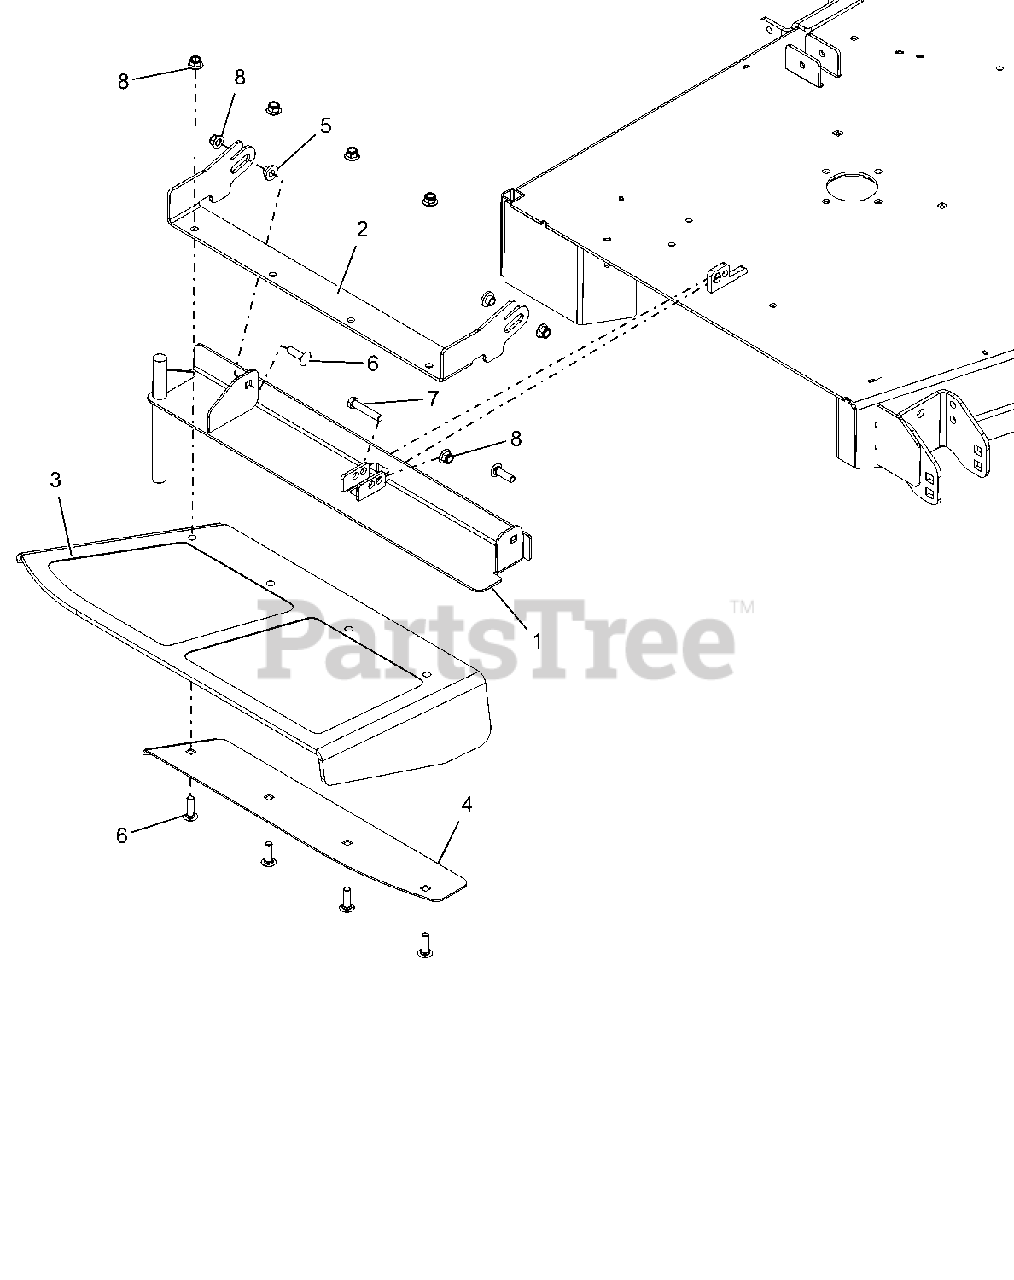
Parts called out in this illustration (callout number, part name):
1	72"DISCH CHUTE MTG WMT W/SAFE
2	72" CHUTE MTG BRKT - RED
3	CHUTE, 72" FORMED RUBBER DISCH
4	PLATE, 72" DISCH CHUTE CLAMP
5	BSHG-FLG .385X.500X.875X.406
6	BLT-RHDSSQNK .38-16X1.25 G5YZ
7	BLT-HEX .38-16X2.00 GR5 YWZC
8	NUT-LK-NYL-FLG .38-16 YWZC
